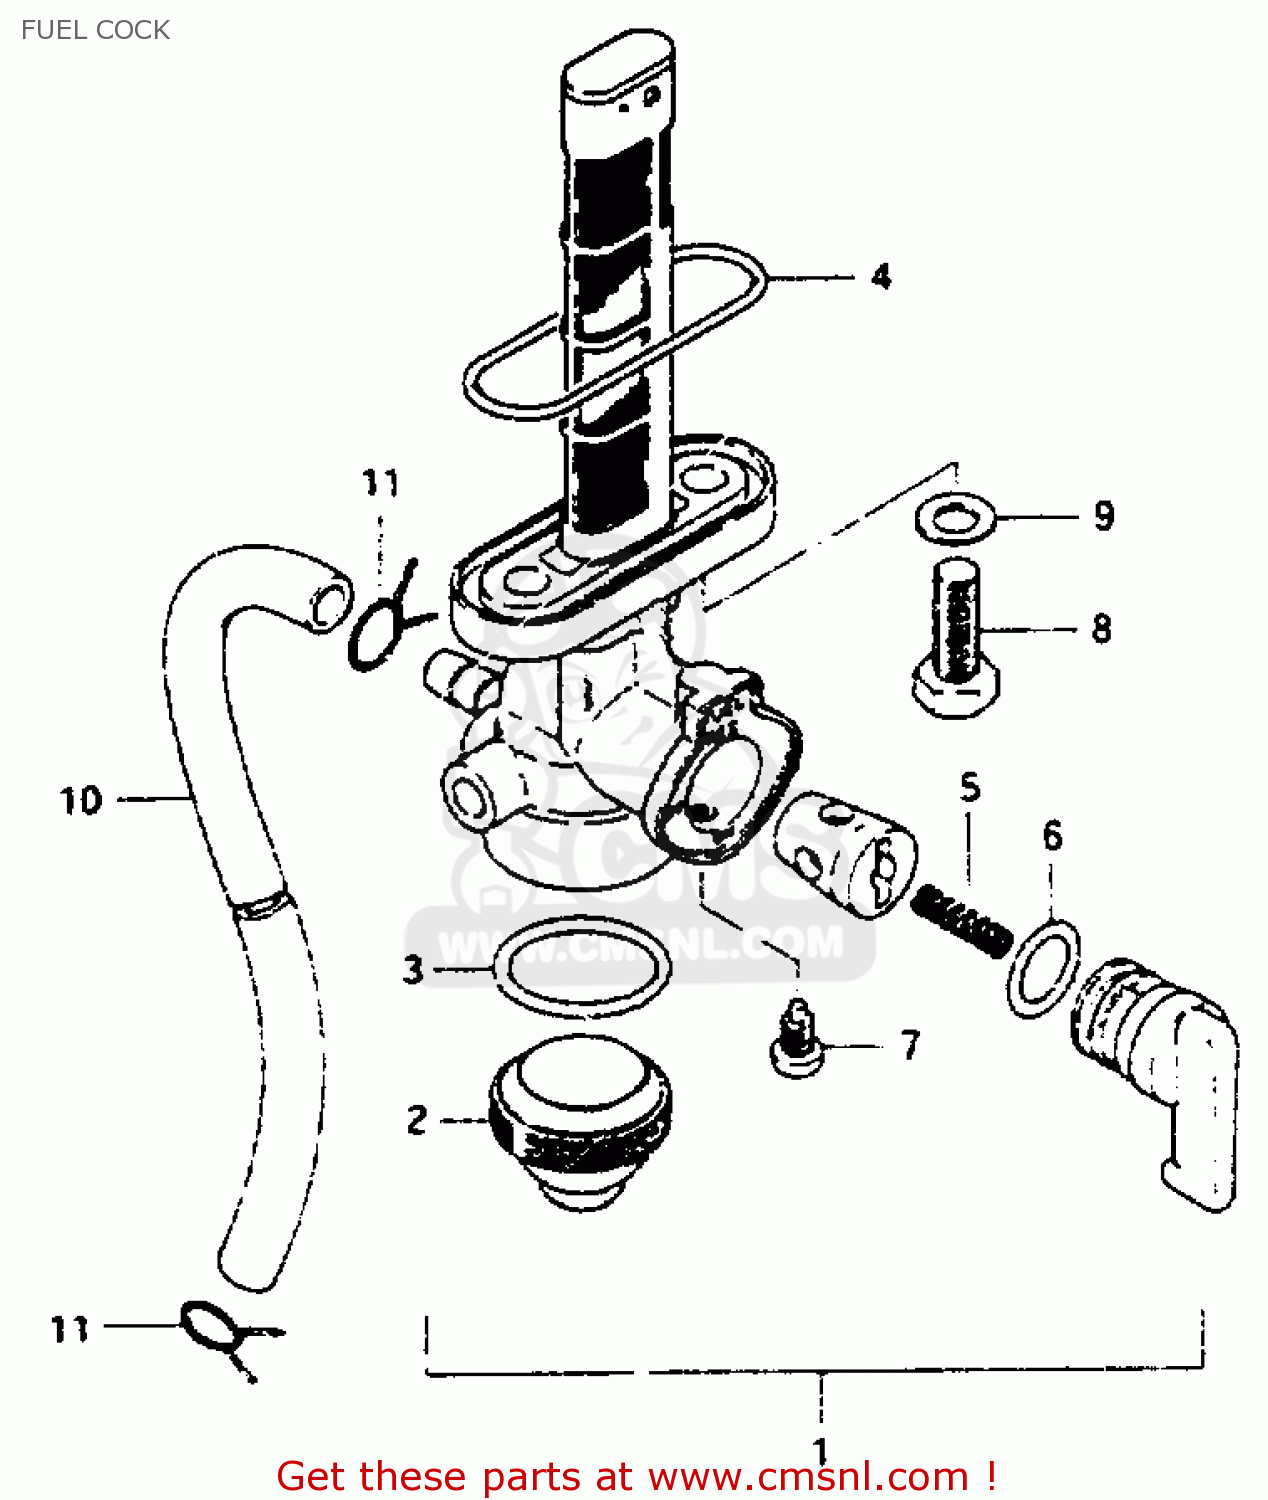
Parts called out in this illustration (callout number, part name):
1	COCK ASSEMBLY,FUEL
2	CUP,STRAINER
3	GASKET,FILTER (NAS)
4	O RING,FUEL COCK
5	SPRING
6	O-RING
7	SCREW
8	BOLT(6X20)
9	GASKET
10	HOSE
11	CLIP
